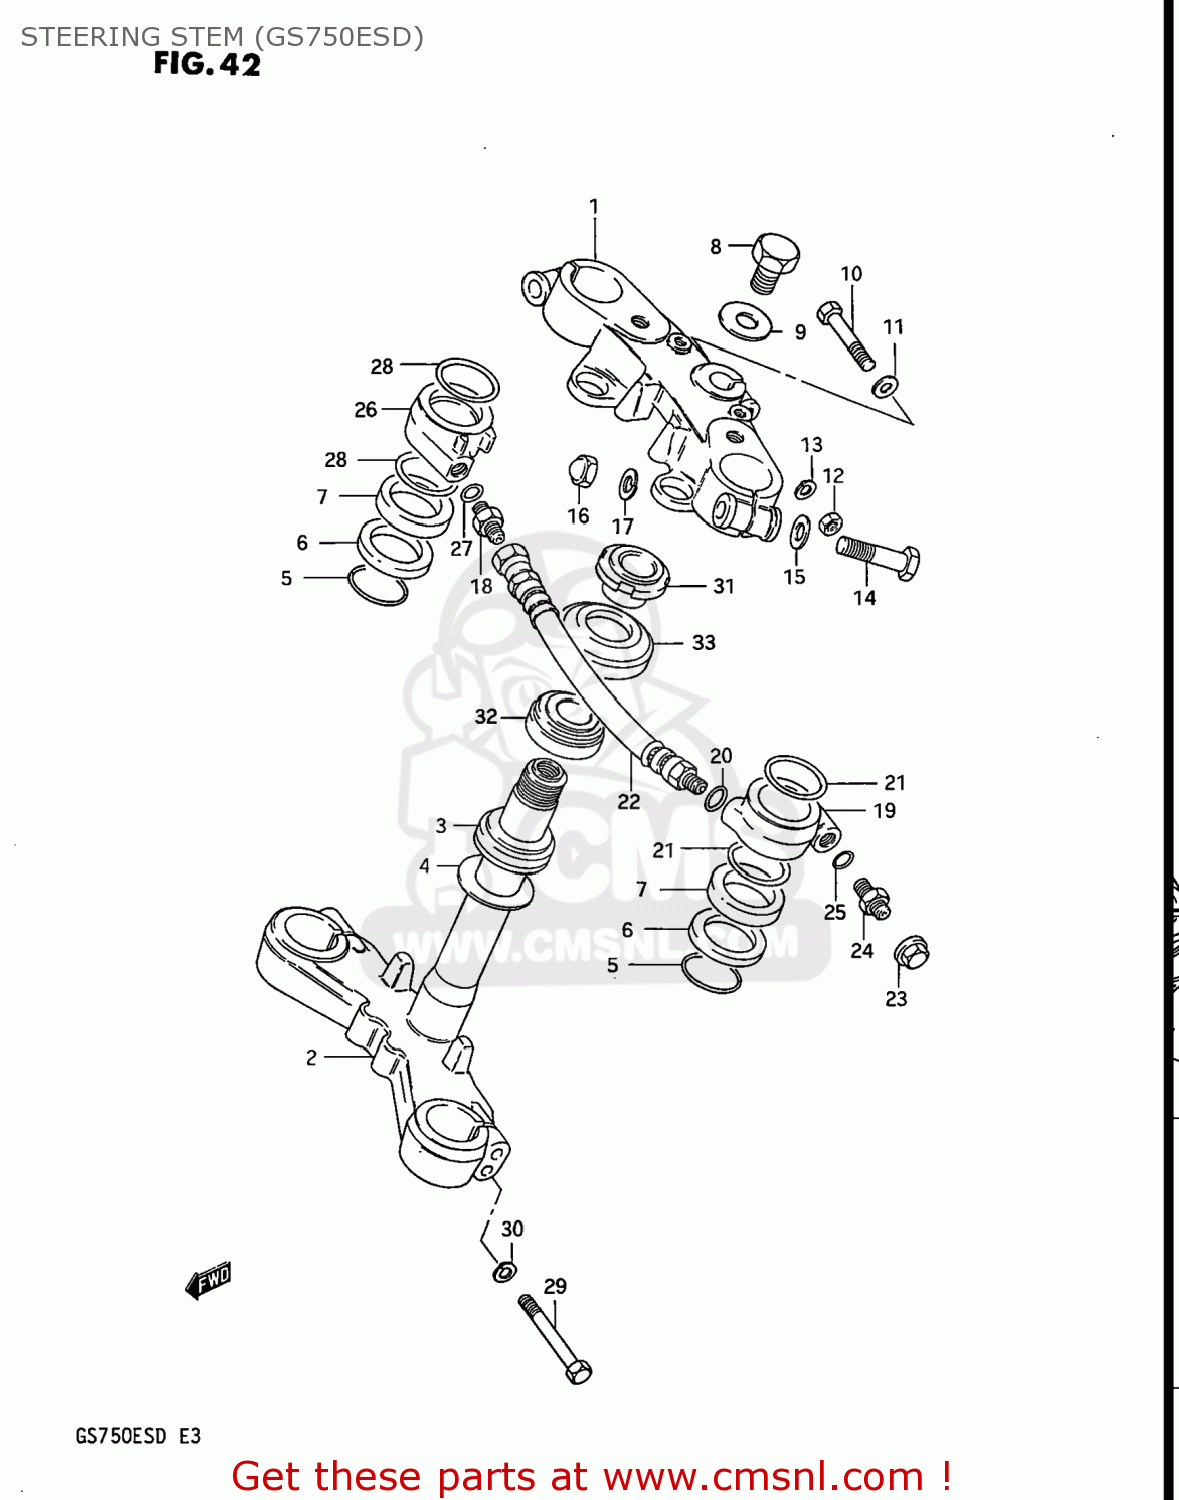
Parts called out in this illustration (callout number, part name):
1	HEAD,STEERING STEM
2	STEM,STEERING
3	BEARING
4	WASHER,THRUST
5	RING,STOPPER
6	WASHER
7	CUSHION
8	BOLT,STEERING STEM HEAD
9	WASHER
10	BOLT 8X50
11	WASHER
12	NUT 8MM
13	LOCK WASHER
14	BOLT 10X55
15	WASHER
16	NUT
17	LOCK WASHER
18	CONNECTOR
19	JOINT,AIR,LEFT
20	O-RING
21	O RING
22	TUBE,JOINT
23	CAP,FRONT FORK AIR VALVE
24	VALVE,AIR
25	O-RING
26	JOINT,AIR,RIGHT
27	O-RING
28	O RING
29	BOLT 8X40
30	LOCK WASHER
31	NUT,STEERING STEM
32	TAPER,ROLLER BEARING
33	DUST SEAL,STEERING UPR
